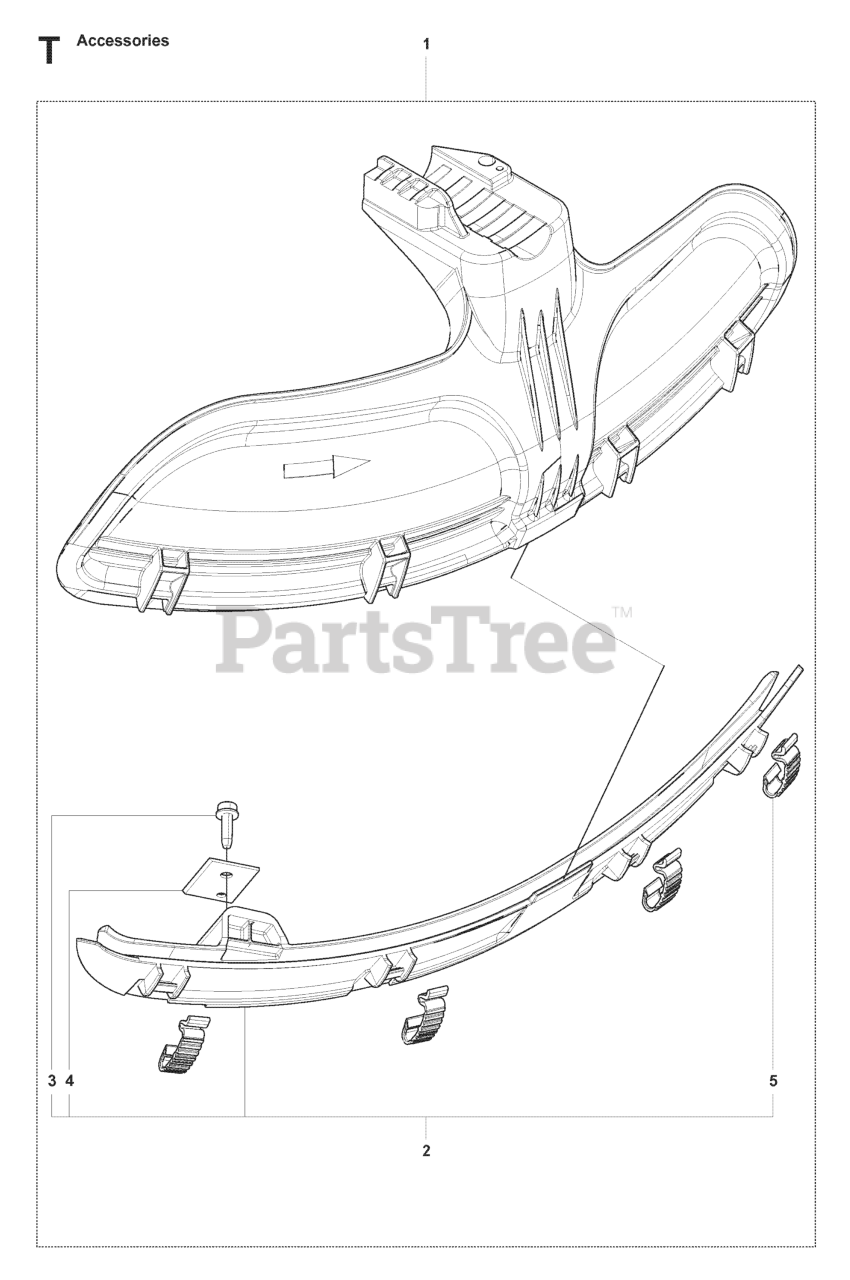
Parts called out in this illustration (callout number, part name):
1	COMBI PROTECTOR
2	SPLASH GUARD
4	LINE CUTTER
